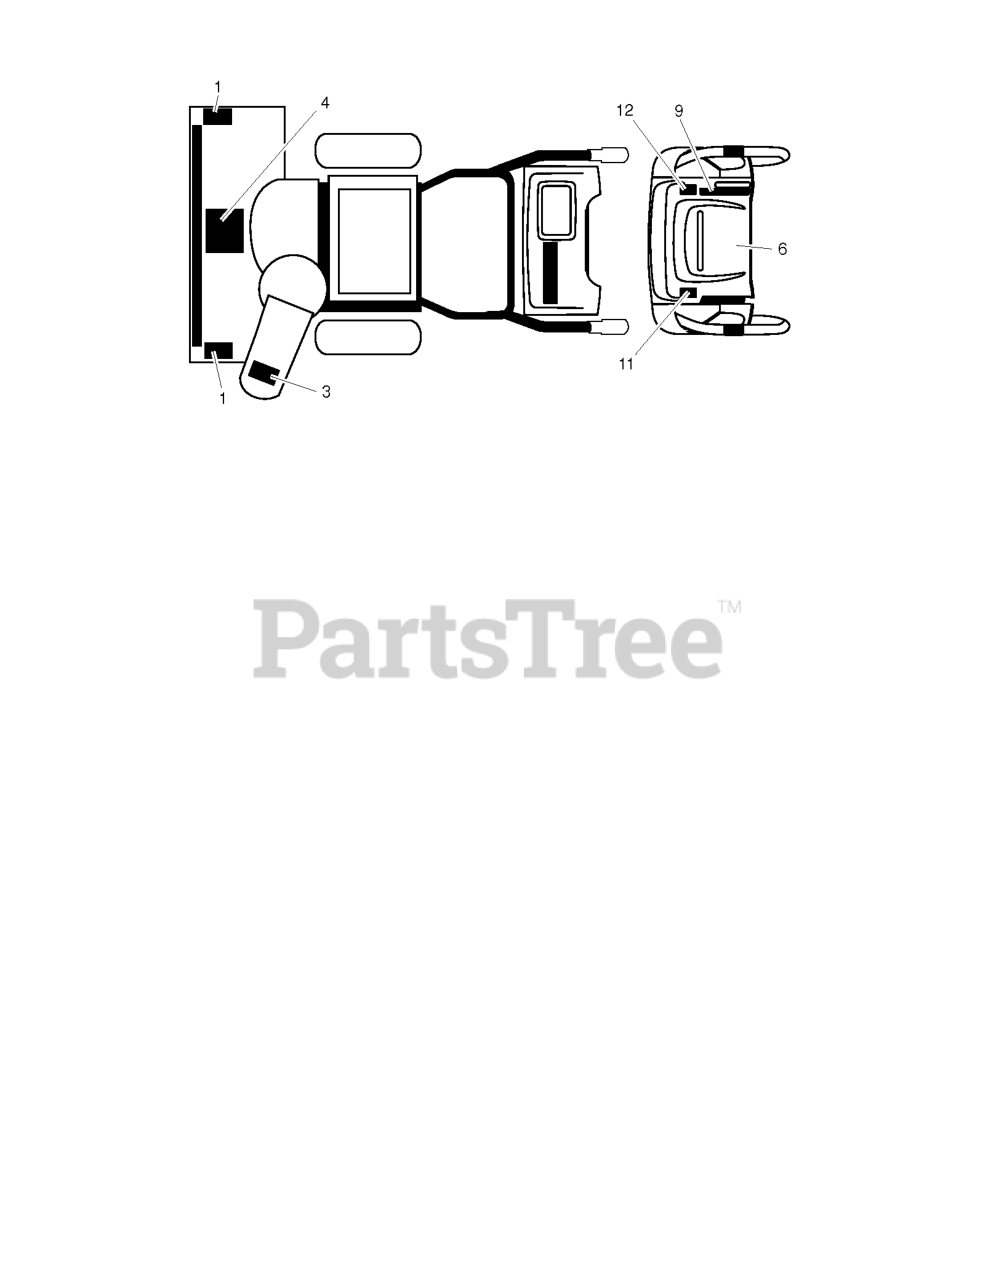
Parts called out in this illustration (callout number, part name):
1	DECAL.SNOWTHR.AUGER
3	DECAL.SNOWTHR.CHUTE.SAFETY
4	DECAL.SNOWTR.READ.OWN.MAN.E/F
6	DECAL, INSTRUCTION
9	DECAL SPEED CONTROL
11	DECAL POWER STEER
12	3ECAL POWER STEER
